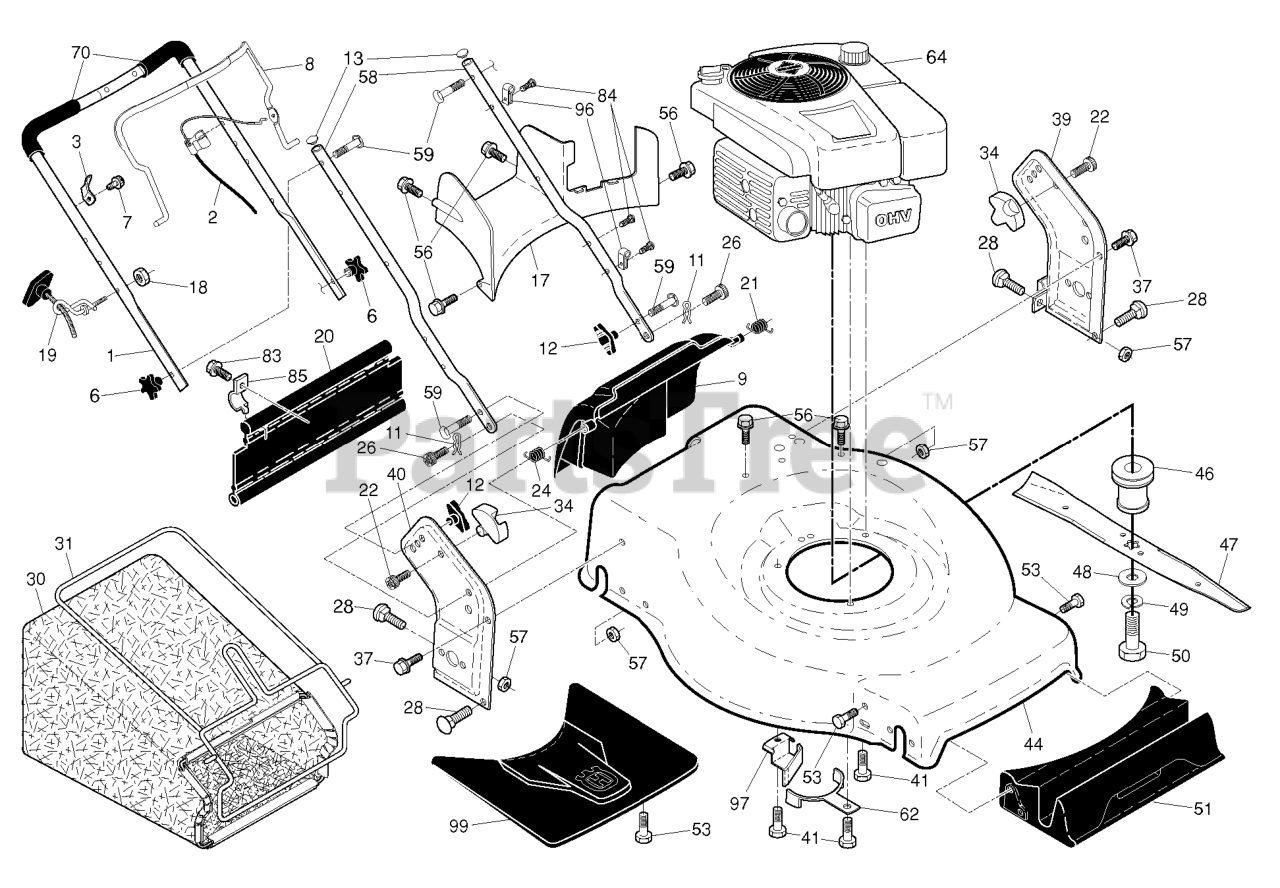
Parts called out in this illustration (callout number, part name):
1	HANDLE.ASM.UPPER.W/GRIP
2	RP.CABLE.MZR.RGD.ERGO.DOV
3	BRACKET.UPSTOP.RT
6	KNOB.HANDLE.PLASTIC.STAR.BLACK
8	BAIL.CONTROL.MZR.BS.ORANGE
9	DOOR.REAR.ASM.22+.HUSQ.FG/RGD
11	COTTER.HAIRPIN.DOOR/HANDLE.PIV
12	KNOB, DEFLECTOR
13	PLUG.PLASTIC.7/8".14-20.GAUGE
17	RP.BAFFLE.REAR.22+.RGD.PL
18	NUT
19	RB GUIDE.ROPE.STD.BLK.ZIN WSL
20	SKIRT.REAR.22+.RGD.HW
21	SPRING.LH.BLACK
22	SCREW.PAN.HEAD.#10
24	SPRING.RH.GRAY
26	SCREW,DOOR/HANDLE.PIVOT
28	BOLT
30	GBAG.A3610247T.SILV.HUSWT.BLUE
31	RB FRAME.GBAG.22PLUS
34	BRACKET.GRASSBAG.ATTACHING.BLK
37	BOLT.5/16HEX.WHS.HD
39	BRACKET.HANDLE.LT.22+.W/DP.GRE
40	RP.BRACKET.ASM.HANDLE.RT.22+.
41	BOLT 3/8-16X1-1/8
44	HOUSING.22+.RWD.WO/PORT.ORANGE
46	ADPTER.BLAD.25M.VS.22PLU.STAR
47	BLADE.22+FUSION.PREM/PREC
48	WASHER,HARDEN
49	LOCKWASHER
50	SCREW, HEX HD 3/8-24 X 1-3/8
51	BAFFLE.FRONT.22PLUS.PLASTIC RP
53	SCREW.HI-LO.5/16 X.75
56	SCREW.HX.13X.750
57	NUT.FLANGE.5/16
58	HANDLE.LOWER.22+BT.2PC.GRY
59	BOLT, HANDLE 5/16-18X1.75
62	BRACKET.ENG/BELTKEEPER
70	GRIP.HANDLE.FOAM.WIDE.(1 SIDE)
83	TAPPING SCREW
84	FASTENER.PUSH.O.250X0.783
85	BRACKET.SKIRT.22+.BZP
96	CLIP.CABLE.BLK
97	BRACKE.BELT.GUIDE.22+
99	COVER.ASM.FRONT.SHROUD.HUSQ.
